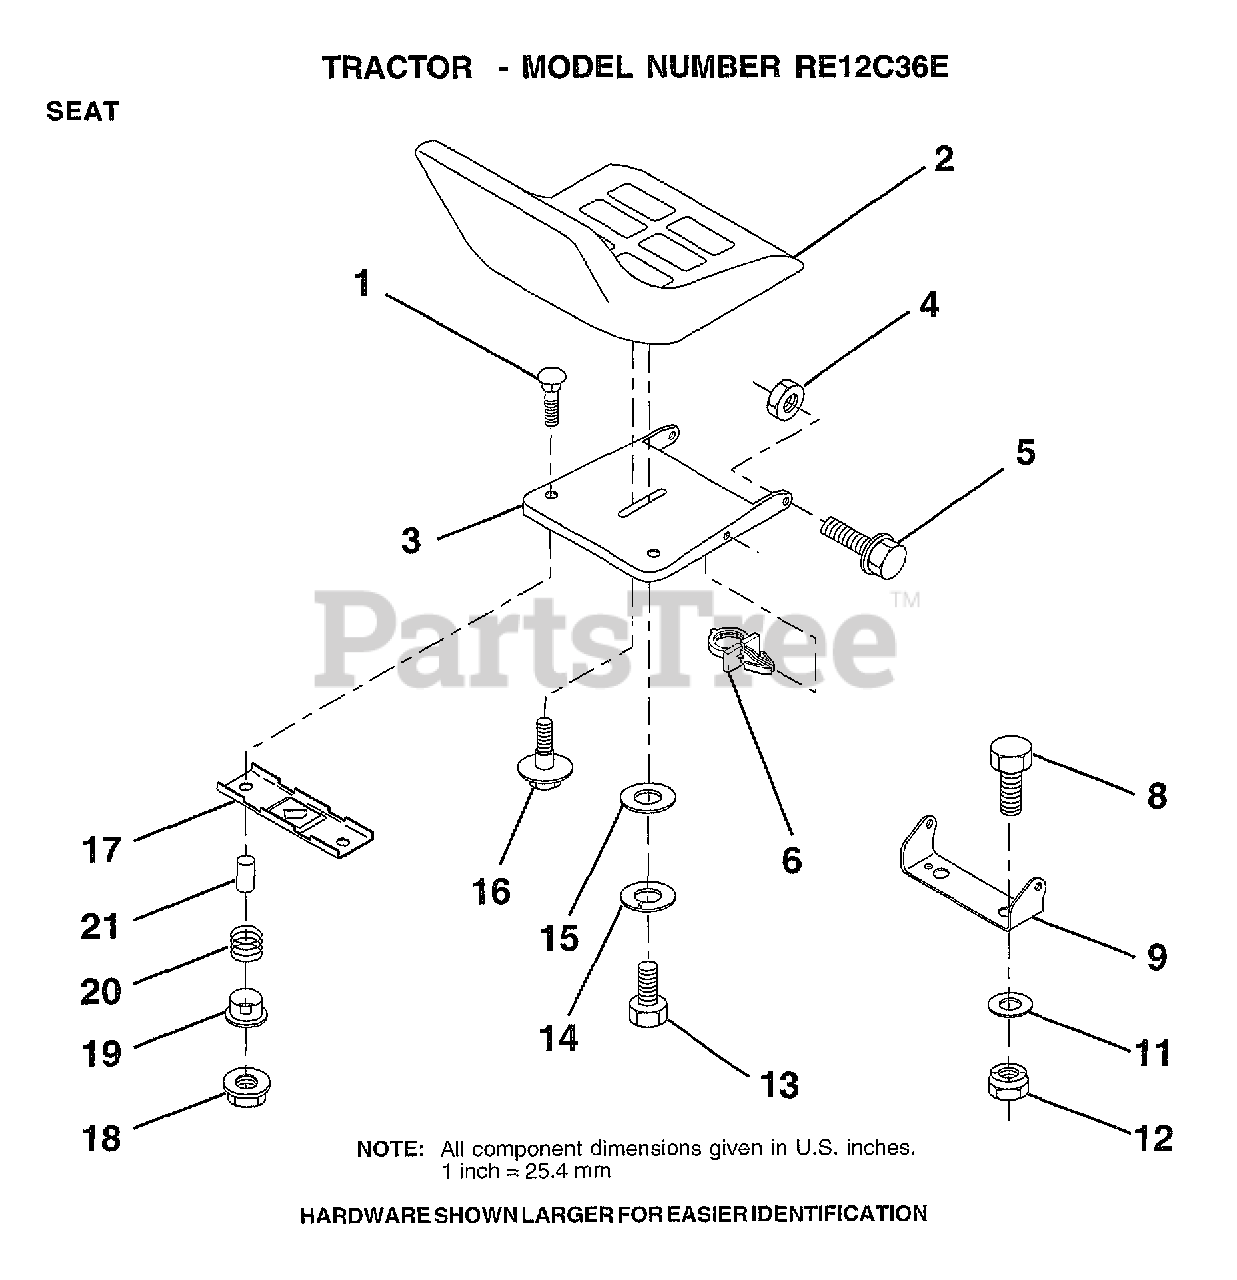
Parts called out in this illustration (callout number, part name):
1	BOLT-RD HD SQ NK
3	PAN-SEAT
4	NUT
5	BOLT
6	CLIP.PUSH-IN.HING
8	BOLT
9	BRACKET PVT SEAT
11	WASHER
12	NUT
13	BOLT
14	LOCKWASHER
15	WASHER
16	"BOLT,SHOULDER"
17	BRKT SWITCH
19	BUSHING
20	SPRING
21	SPLIT SPACER
